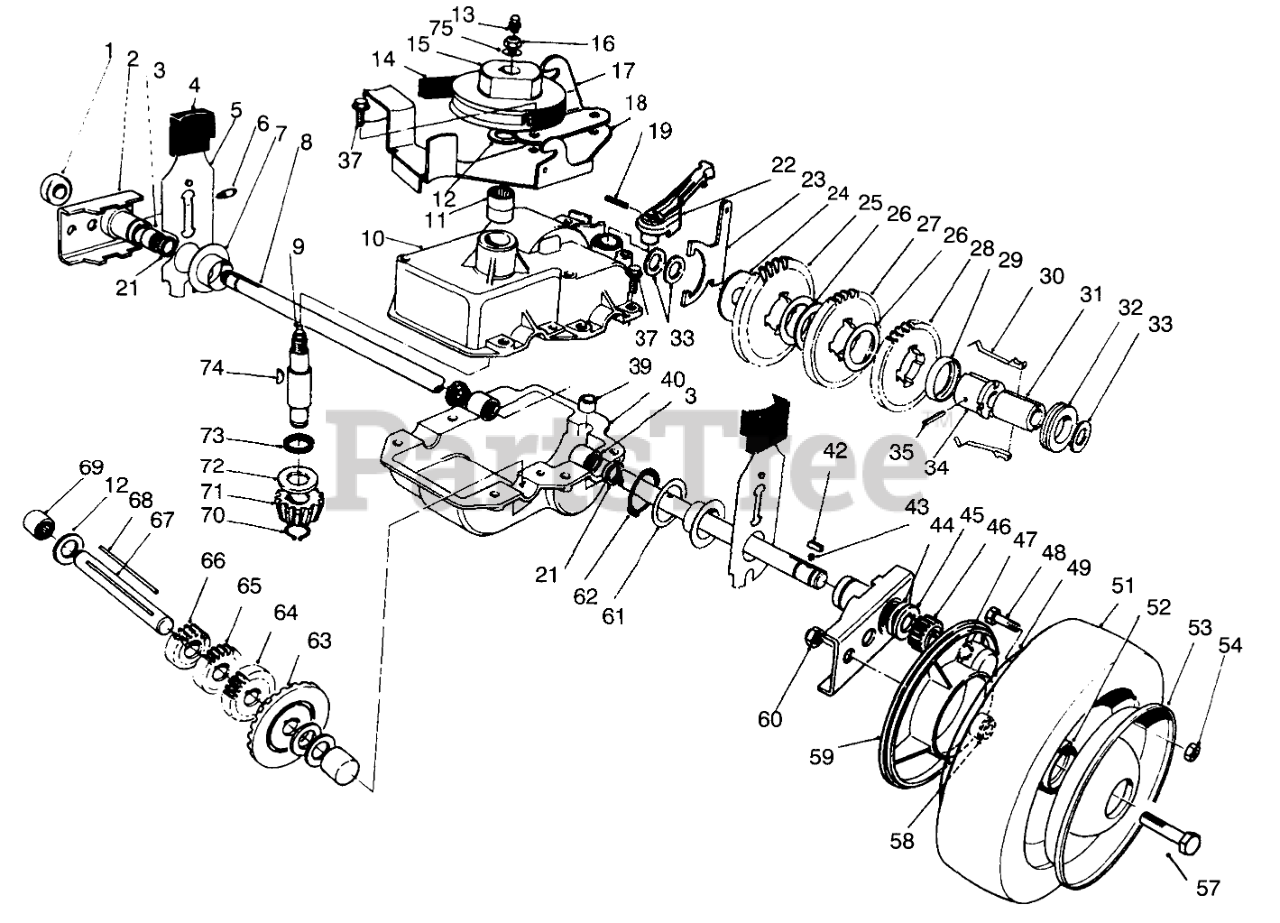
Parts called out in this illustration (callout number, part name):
1	BEARING-WHEEL
2	Pivot Arm Assembly (Incl. Ref. #1, 3, 6 & 21)
3	BEARING-ROLLER
4	KNOB-ARM
5	REAR SPRING ARM ASM
7	CAP-END
8	SHAFT-OUTPUT
9	Shaft-Input (Incl Ref. #13)
10	Upper Case Assembly (Incl. Ref. #11 & 73)
11	BEARING-NEEDLE
12	WASHER-THRUST
13	FITTING-GREASE, ZERK
14	V-BELT
15	PULLEY
16	NUT-HEX
17	Bracket-Traction Engage
18	Belt Guide Bracket
19	PIN-COIL
21	SEAL-OIL
22	LEVER-SHIFT
23	YOKE-SHIFT
24	WASHER
26	WASHER
27	GEAR-42T
28	GEAR-38T
29	RETAINER-KEY
30	KEY-SHIFT
31	SLEEVE
32	COLLAR-SHIFT
33	WASHER-PLAIN
34	SLEEVE-GEAR
35	PIN-GROOVE
37	SCREW-HWHTF
39	BUSHING-YOKE
40	CASE-GEAR, LOWER
42	KEY RECTANGULAR
43	SPRING-COMPRESSION
44	WASHER-THRUST, OUTER
45	WASHER-THRUST, OUTER
46	GEAR-PINION
47	RING-RETAINING
48	SCREW-HH
49	Wheel-Half
52	Hub Ass-y
53	Wheel-Half
54	NUT-LOCK, NI
57	SCREW-HH
58	SPACER-COVER, WHEEL
59	COVER-WHEEL
60	NUT-LOCK, CONE
61	WASHER
62	RING-RETAINING
63	GEAR-BEVEL
64	GEAR-18T
65	GEAR-14T
66	GEAR-12T
67	SHAFT-INTERMEDIATE
69	BEARING-NEEDLE, CLOSED
70	RING-RETAINING
71	PINION-BEVEL
72	WASHER-THRUST
74	KEY-WOODRUFF
75	WASHER-FLAT
